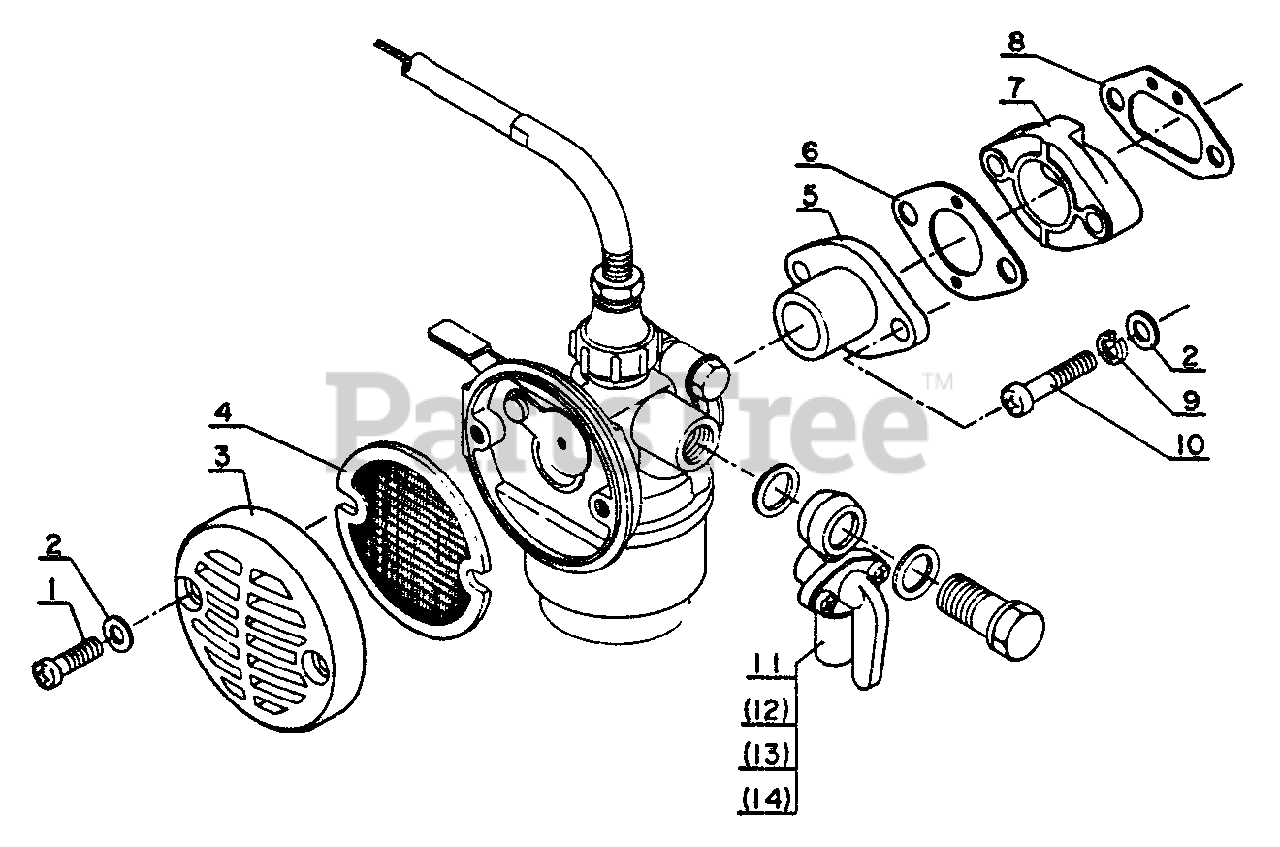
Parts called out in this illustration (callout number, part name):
1	SCREW - 4X12
2	WASHER - 4
3	FILTER, AIR
4	COVER, AIR FILTER
5	ADAPTOR, INTAKE
6	GASKET, INTAKE
7	INSULATOR, INTAKE
8	GASKET, INTAKE
9	LOCKWASHER - 4
10	SCREW - 4X25
11	FUEL VALVE ASSY
